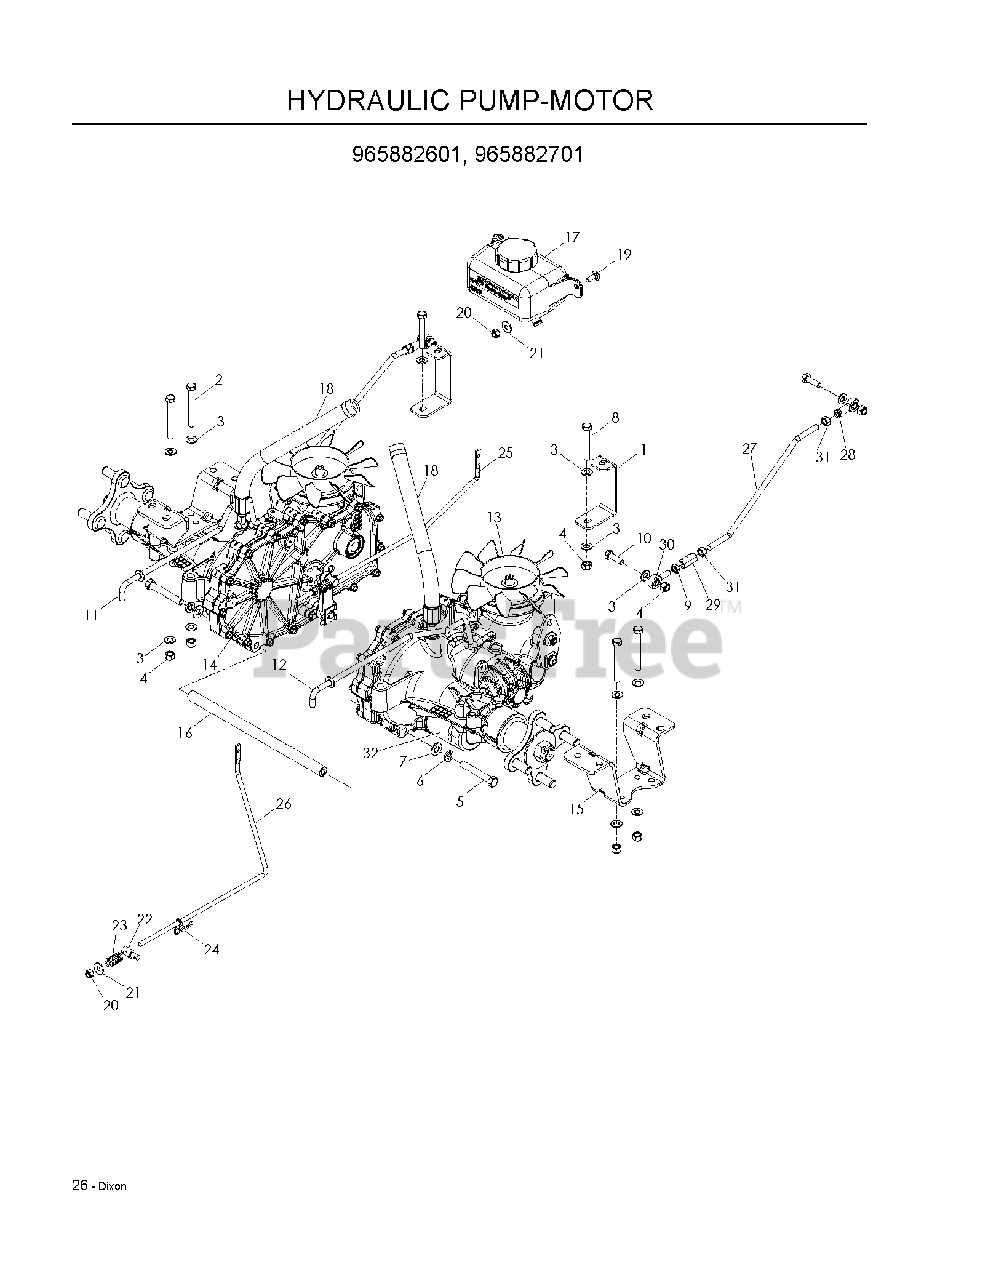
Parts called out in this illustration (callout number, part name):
1	SUPPORT.FRONT.TRANS.BLACK.
2	HCS 5/16C X 2-3/4
3	FLAT WASHER 5/16 SAE
4	NUT 5/16 NYLOC
5	HCS 3/8C X 2 1/2
6	SLW 3/8 STD
7	WASHER 3/8 SAE FLAT
8	CAPSCREW
9	NUT 5/16F LEFTHAND
10	HCS 5/16C X 1
11	ROD, BYPASS, RT
12	ROD, BYPASS, LT
13	HG_TRANS, ZT-2800 RT
14	HG_TRANS, ZT-2800 LEFT
15	EZT MOUNT, REAR, BLACK
16	SPACER TUBE, EZT, 11.08
17	HG_EXPANSION TANK W/CAP
18	HOSE ASSY
19	RHSNB 1/4C X 3/4
20	NUT 1/4-20 NYLOC
21	WASHER 1/4 FLAT
22	BRAKE SWIVEL
24	HAIRPIN #2
25	ROD EZT BRAKE LT
26	ROD EZT BRAKE RT
27	ROD, MOTION CONTROL
28	RH ROD END
29	ROD END COUPLER
30	ROD.END.LH
31	NUT 5/16F
32	HG_FILTER, ZT4800
